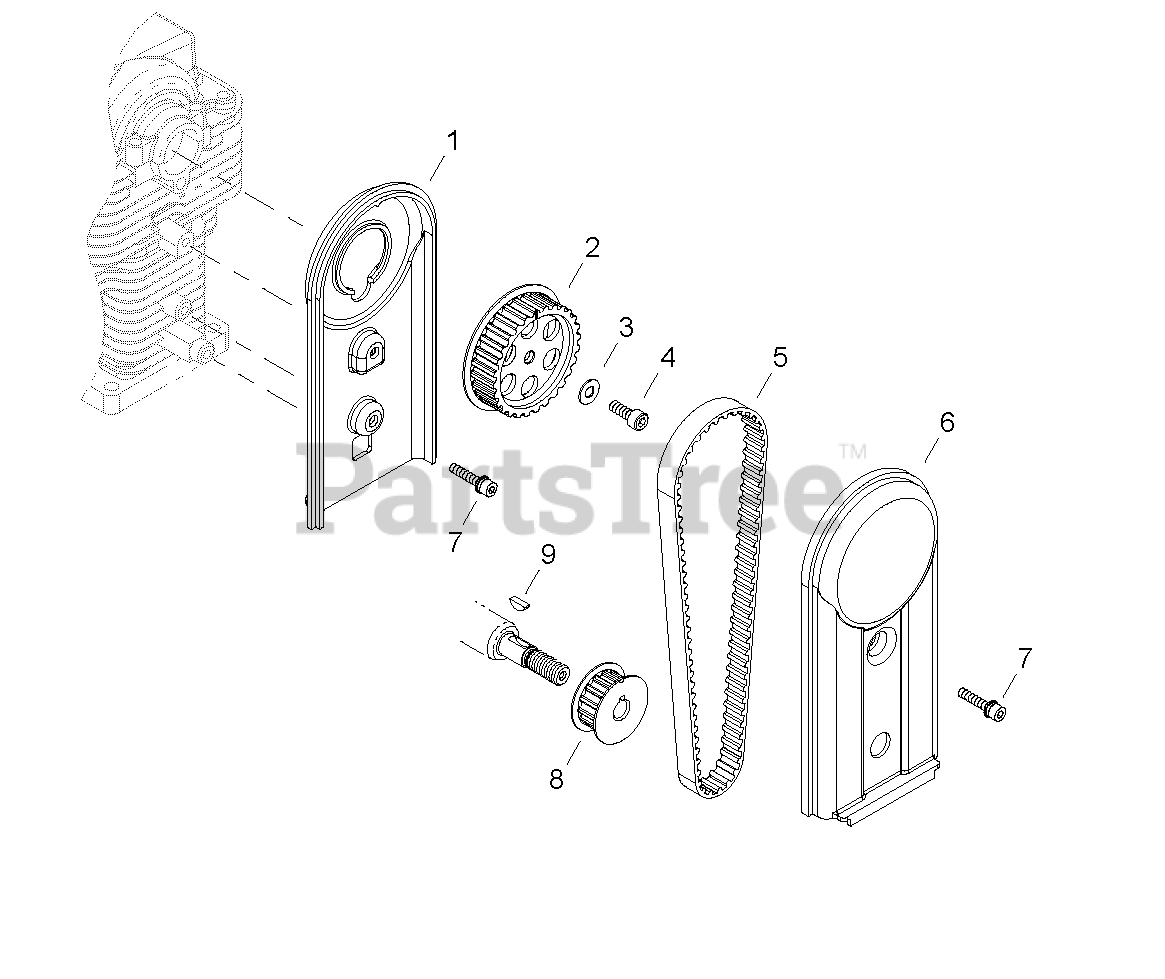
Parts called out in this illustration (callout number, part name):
1	CASE, BELT
2	PULLEY, CAM
3	WASHER - 5
4	SCREW - 5X14
5	BELT
6	COVER, BELT
7	SCREW - 5X12
8	CRANK PULLEY
9	KEY - 3X10
